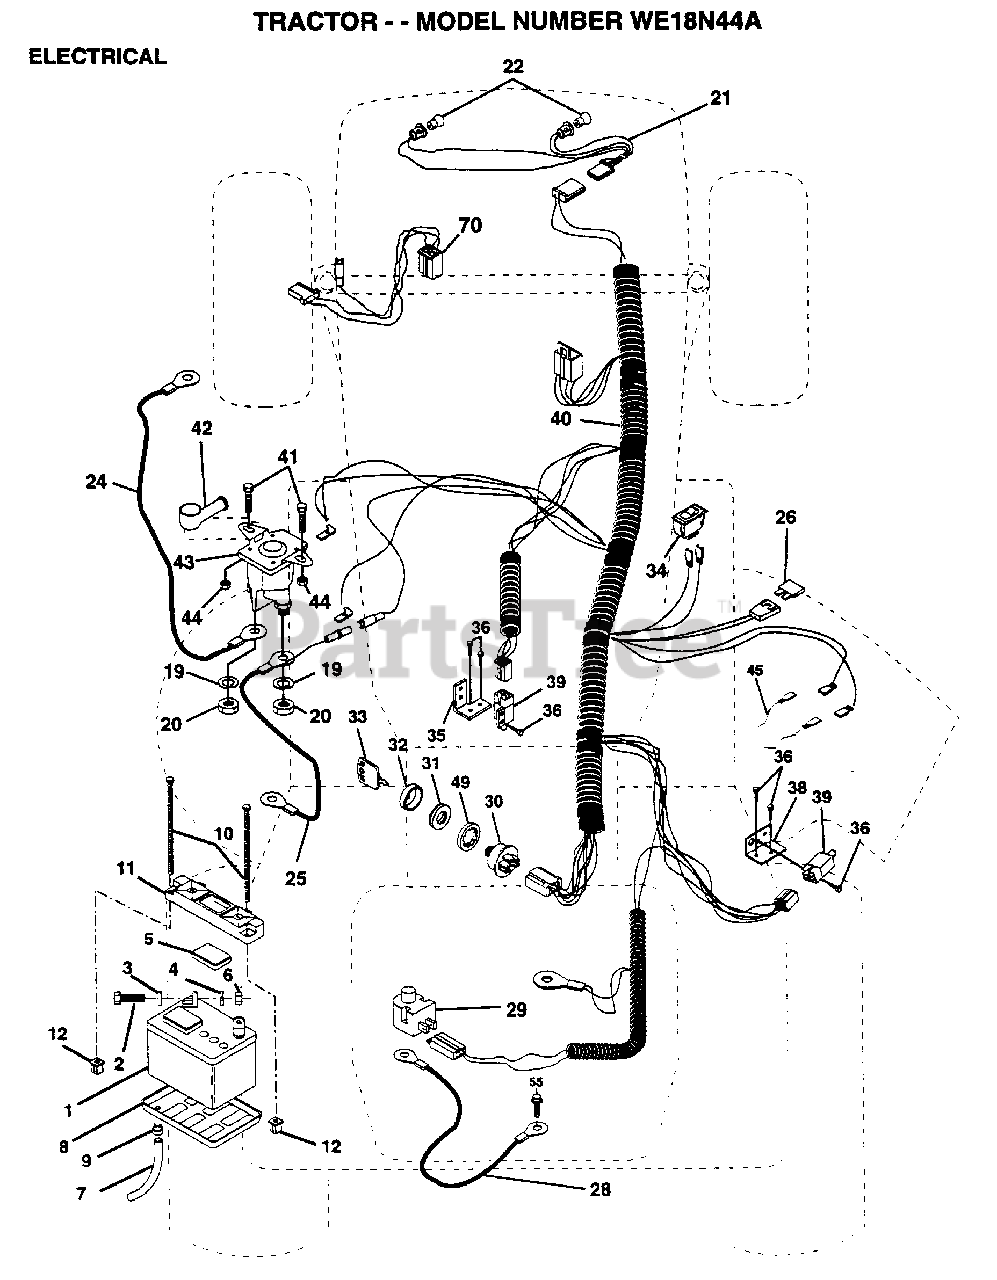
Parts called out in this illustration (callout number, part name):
2	BOLT LT
3	WASHER
4	LOCKWASHER
5	"CAP,BATTERY "
7	"DRAIN TU T, BATT"
8	"TRAY T, BATTERY"
9	HOSE CLAMP T
20	NUT
21	"HARNESS,LIGHT SOC"
22	HEADLAMP BULB
24	"CABLE T, BATTERY"
25	CABLE.6GA.22W/16W
26	FUSE HYT
28	CABLE.GRND.6GA.21
29	SWITCH SEAT
32	COVER KEY SWITCH
33	KEY MLD GEN DELTA
34	SWITCH LT
35	BRACKET LT
36	SCREW
38	BRACKET SWITCH IN
39	SWITCH INTERLOCKT
40	HARNESS.IGN.DASH.
41	BOLT.HX.1/4-20
44	NUT
45	ADAPTER AMMETER
49	LOCKWASHER
55	SCREW LT
70	HARNESS ENGINE
